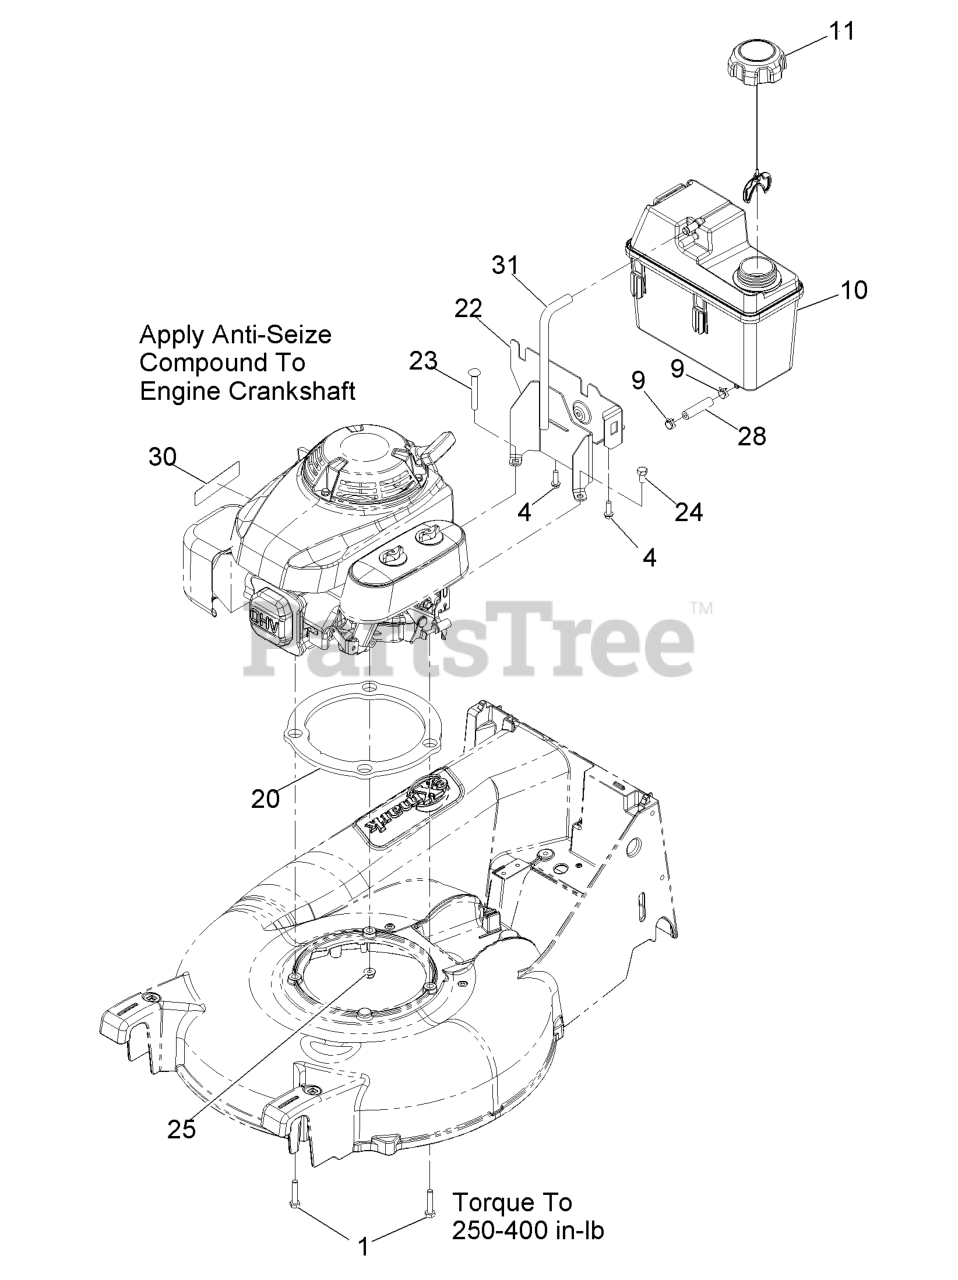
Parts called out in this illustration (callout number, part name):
1	SCREW-HH
4	SCREW-HWH
9	CLAMP-HOSE
10	TANK-FUEL
20	GASKET,DECK
23	SCREW-CARR
24	SCREW-HH
25	NUT-HF, NI
28	HOSE-FUEL
30	DECAL-ARRESTER, SPARK
31	HOSE-VENT, CANISTER
